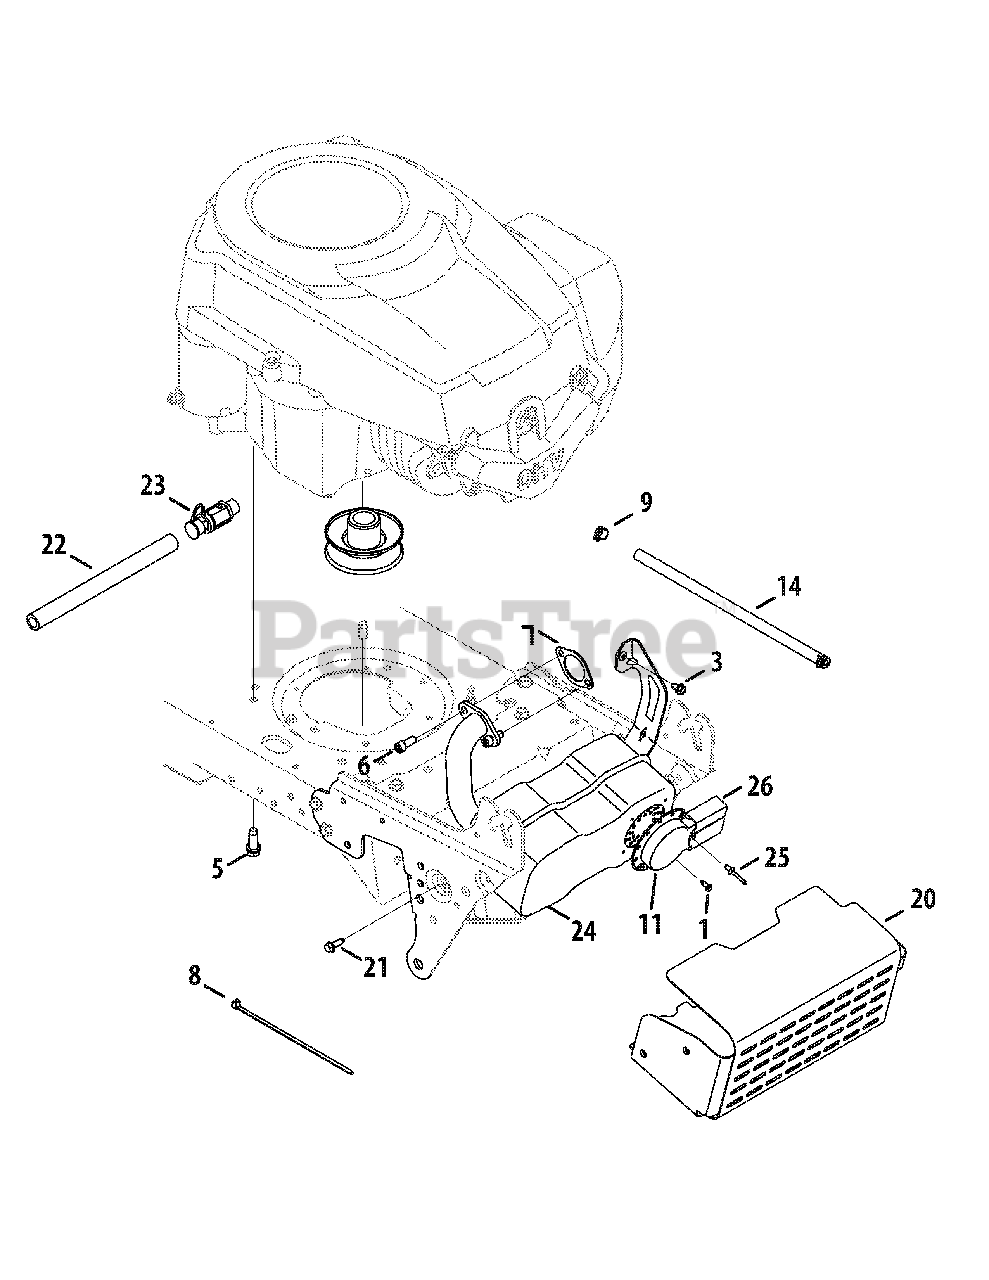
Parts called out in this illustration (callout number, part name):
1	Hex Wash HD AB S-Tapp Scr #8-.50
3	Hex Wash S-Tapp Scr 1/4-20 x .50
5	TT Screw 3/8-16 x 1.0
6	Sems Hex Nut 1/4-20
7	Exhaust Gasket
11	Muffler Deflector
14	Fuel Line
21	Thd Forming Scr. 1/4-20 x .75 Lg.
22	Oil Drain Ext. Hose
23	Oil Drain
24	Muffler
26	Muffler Deflector, Long
